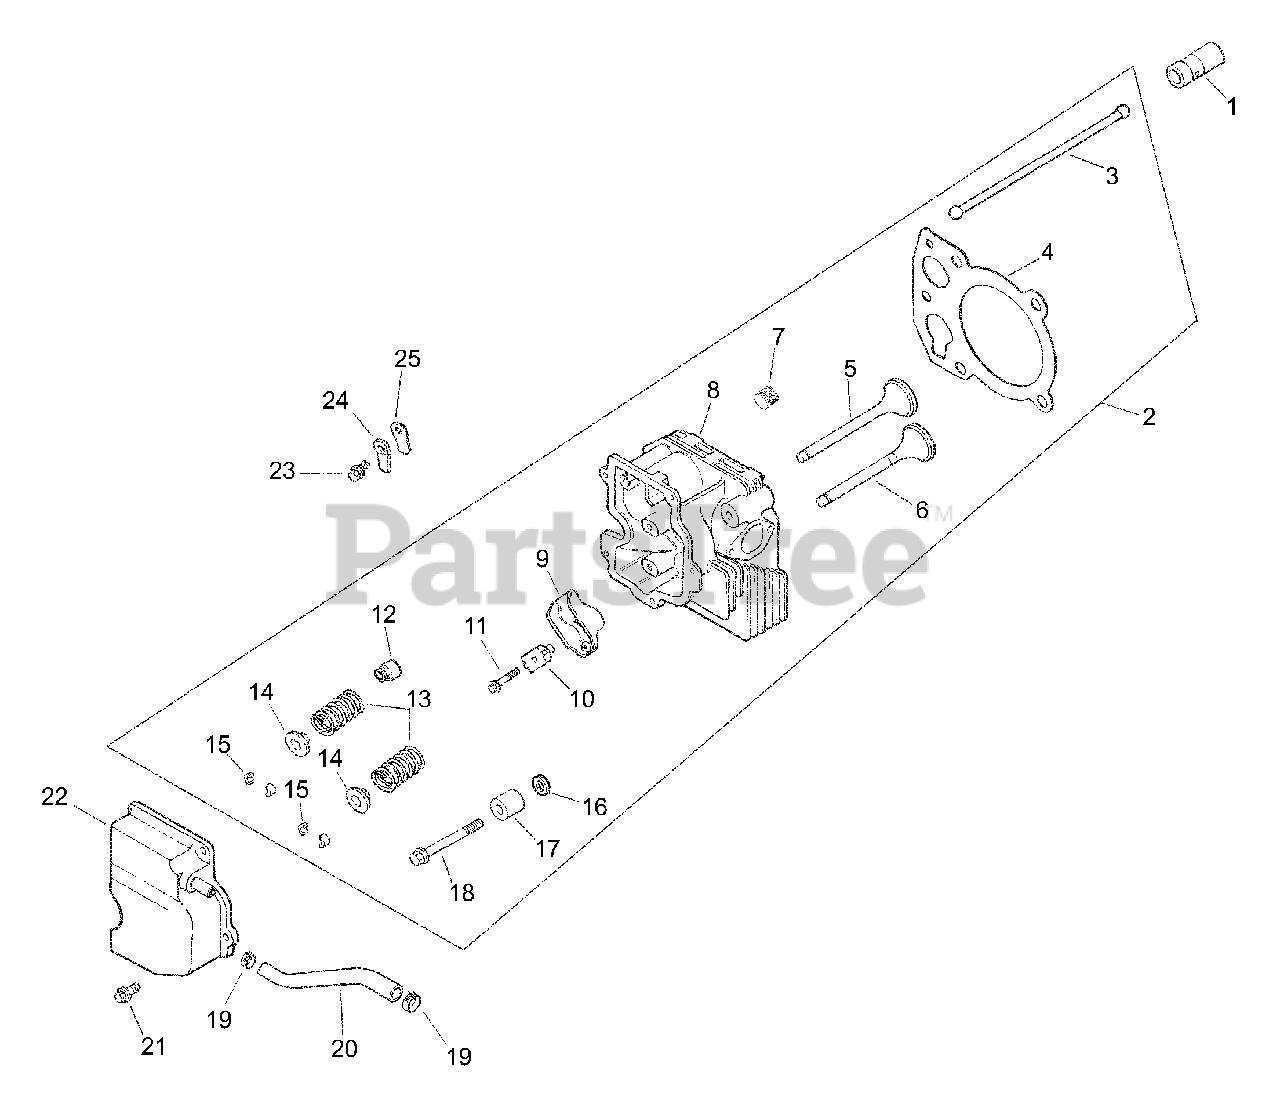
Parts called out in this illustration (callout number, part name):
1	Lifter, Valve
2	Kit, Cylinder Head
3	Rod, Push
4	Gasket, Cylinder Head
5	Valve, Intake (Std.)
6	Valve, Exhaust (Std.)
7	Plug, Allen Hd. 1/8" Pipe
8	Cylinder Head
10	Pivot, Rocker Arm
11	Screw, Hex. Flange M6 x 1.0 x 34
12	Seal, Valve Stem
13	Spring, Valve
14	Cap, Valve Spring
15	Kit, Retainer
16	Washer, Plain 13/32"
17	Spacer, Head Bolt Exhaust Port
18	Screw, Hex. Flange M10 x 1.5 x 81
19	Clamp, Hose
20	Hose, Breather
21	Screw, Hex. Flange M6 x 1.0 x 20
22	Cover, Valve W/nipple
23	Screw, Hex. Flange M5 x 0.8 x 10
24	Retainer, Breather Reed
25	Reed, Breather
